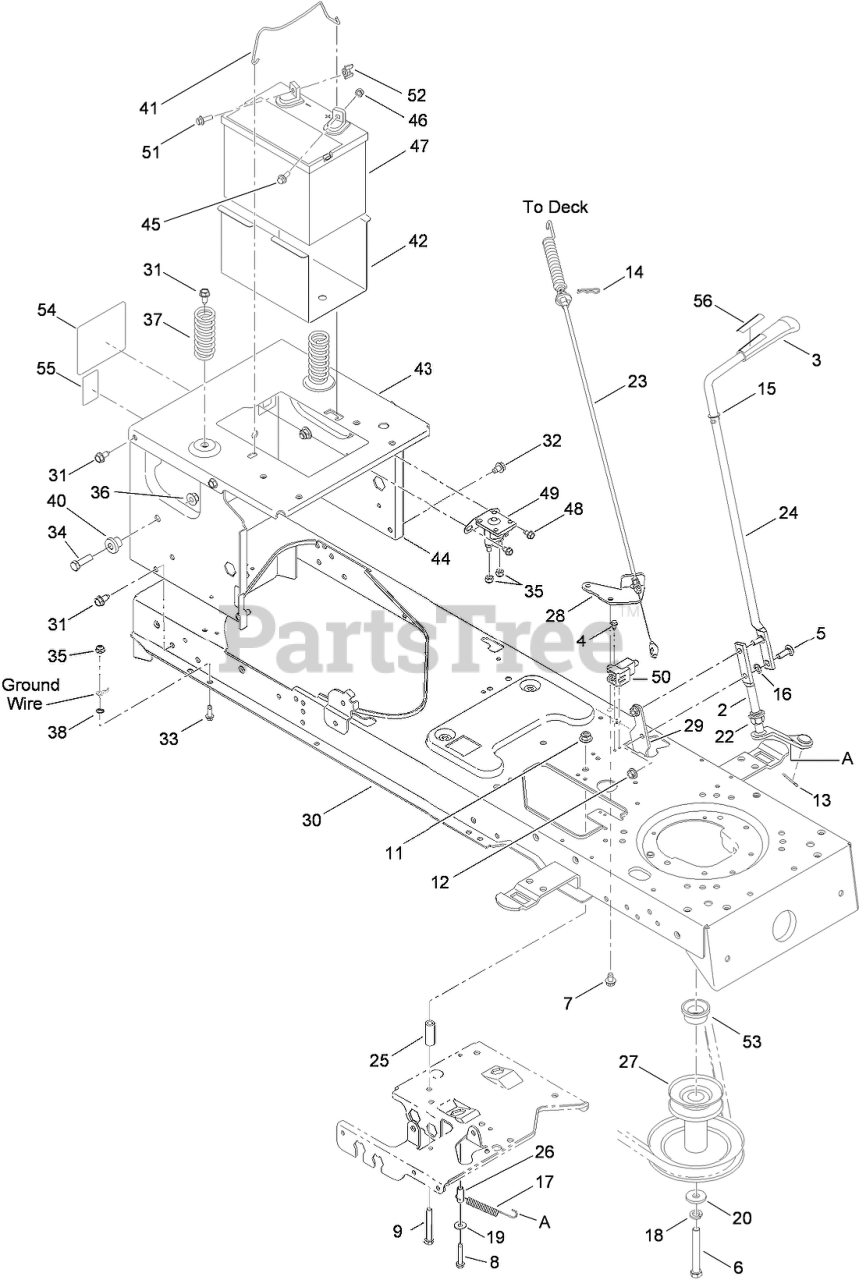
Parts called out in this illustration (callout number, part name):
2	LEVER-ENGAGE, PTO
3	KNOB-PTO
4	BOLT-SHOULDER
5	BOLT-CARR
6	SCREW-HH
7	SCREW-TAP
8	SCREW-HWH
9	SCREW-HH
11	NUT-LOCK, FLANGE
12	NUT-LOCK, FLANGE
13	PIN-COTTER
14	PIN-CLICK
15	WASHER-FLAT
16	NUT-PUSH
17	SPRING-EXTENSION
18	WASHER-LOCK
19	WASHER-FLAT
20	WASHER-FLAT
22	BEARING-FLANGE, HEX (SPLIT)
23	CABLE-ENGAGE, DECK
24	HANDLE-ENGAGE, DECK
25	SPACER
26	SPACER
27	PULLEY-ENGINE
28	BRACKET-MOUNT, CABLE
29	BRACKET-STOP
30	LOWER FRAME ASM
31	SCREW-TAP
32	SCREW-TAP
33	SCREW-TAP
34	SCREW-HH
35	NUT-LOCK, FLANGE
36	NUT-LOCK, FLANGE
37	SPRING-COMPRESSION
38	WASHER-LOCK, EXTERNAL
40	SPACER-SHOULDER
41	ROD-HOLDDOWN, BATTERY
42	TRAY-BATTERY
43	BRACKET-FRAME, SEAT
44	FRAME-UPPER
45	BOLT-CARRIAGE
46	NUT-SEMS
47	BATTERY-245, CCA (DRY FLAT TOP)
48	SCREW-TAP
49	SOLENOID-12V, 2 POST 2 Tab
50	SWITCH-INTERLOCK, NO/NC
51	BOLT-SHOULDER
52	NUT-WING
53	SPACER
54	DECAL-TORO
55	DECAL-HYDRO RELEASE
56	DECAL-PTO
